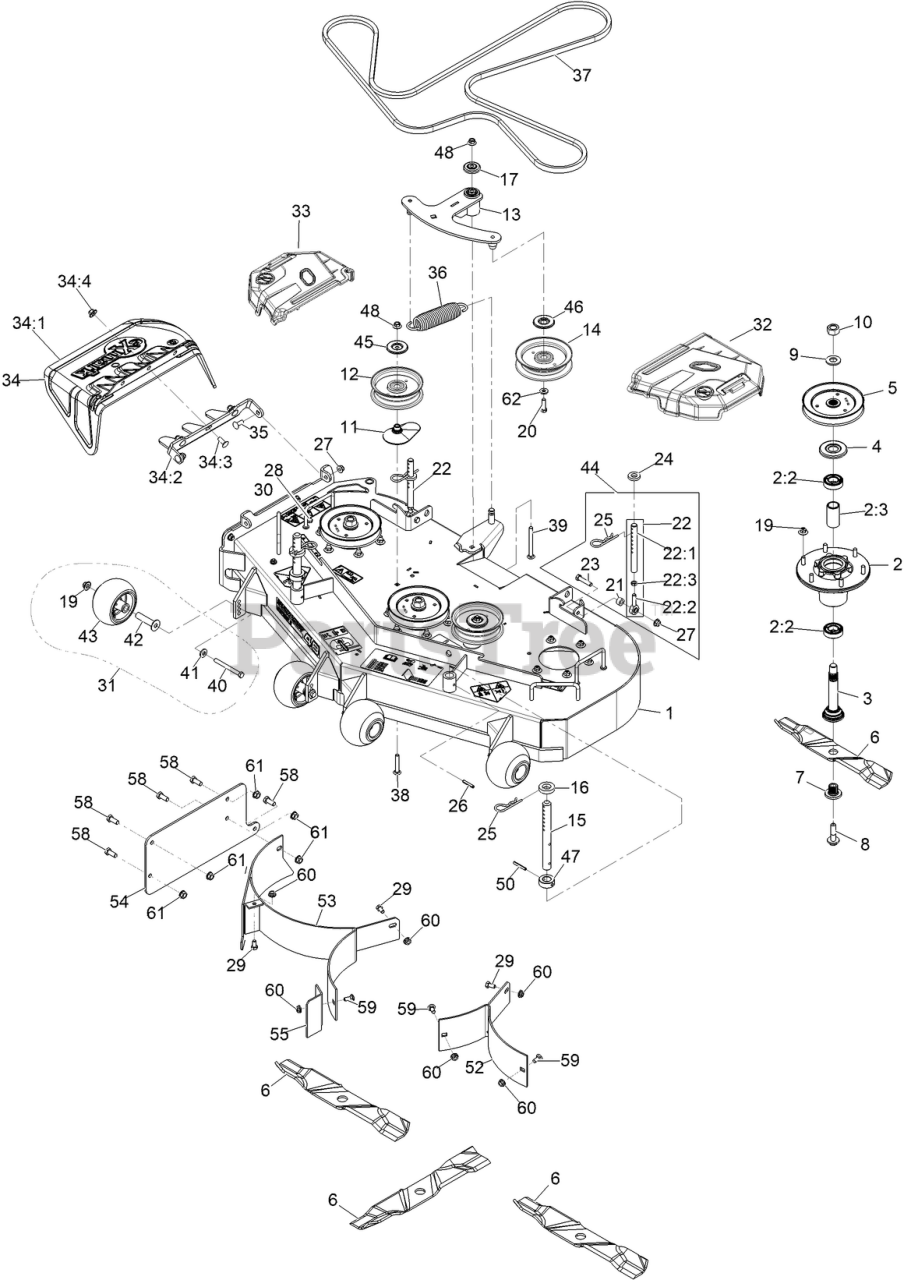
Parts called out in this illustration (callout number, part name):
1	ASM, DECK 48" W/DECALS
2	ASM-CUTTER HSG WITH BEARINGS
2:2	BEARING-BALL
2:3	SPACER-BEARING
3	ASM-SPINDLE AND SEAL
4	GUARD,BEARING TOP .989
5	SHEAVE,BLADE DRIVE 5.90
7	BUSHING,SPLINED
8	SCREW,SEMS 1/2-20 X 2.19
10	NUT-HEX
11	SPACER-PULLEY
12	IDLER-PULLEY, FLAT 5.00X1.31
13	ASM, DECK IDLER
14	IDLER-PULLEY, FLAT
15	ROD, DECK SUPPORT TTS
16	SPACER-DECK SUPPORT
17	GUARD-TOP
19	Nut-Nyloc 3/8-16 Flg
20	SCREW-HH
22:1	LINK,SUPPORT
22:2	BALLJOINT
22:3	NUT-HJ
23	SCREW-HH
25	PIN,HAIR COTTER
27	NUT-HF, NI
28	SCREW-HH
29	SCREW-HH
30	NUT-HF, NI
31	KIT, ANTI-SCALP ROLLER
32	SHIELD, LT
33	SHIELD, RT
34	ASM, DISCHARGE CHUTE
34:1	CHUTE,DISCHARGE
34:2	BRACKET, DISCHARGE CHUTE
34:3	SCREW-CARR
34:4	Nut-Nyloc 3/8-16 Flg
35	SCREW-CARR
36	SPRING-EXTENSION
38	BOLT-CARR, SHORT NECK
39	SCREW-CARR
40	SCREW-HH 3/8-16 X 3 3/4 GR 8
41	WASHER-BELLEVILLE
42	AXLE, ROLLER
43	ROLLER-SCALP, ANTI
44	KIT,SUPPORT LINK W/PIN
45	SHIELD-DUST
46	SHIELD-GUARD, DUST
47	COLLAR, DECK HEIGHT PIN
50	PIN-ROLL
53	BAFFLE-RH
54	PLATE, MULCH COVER
55	BAFFLE-BLOCKER
58	SCREW-HH
59	BOLT-CARR
61	NUT-HHF, WHIZ
